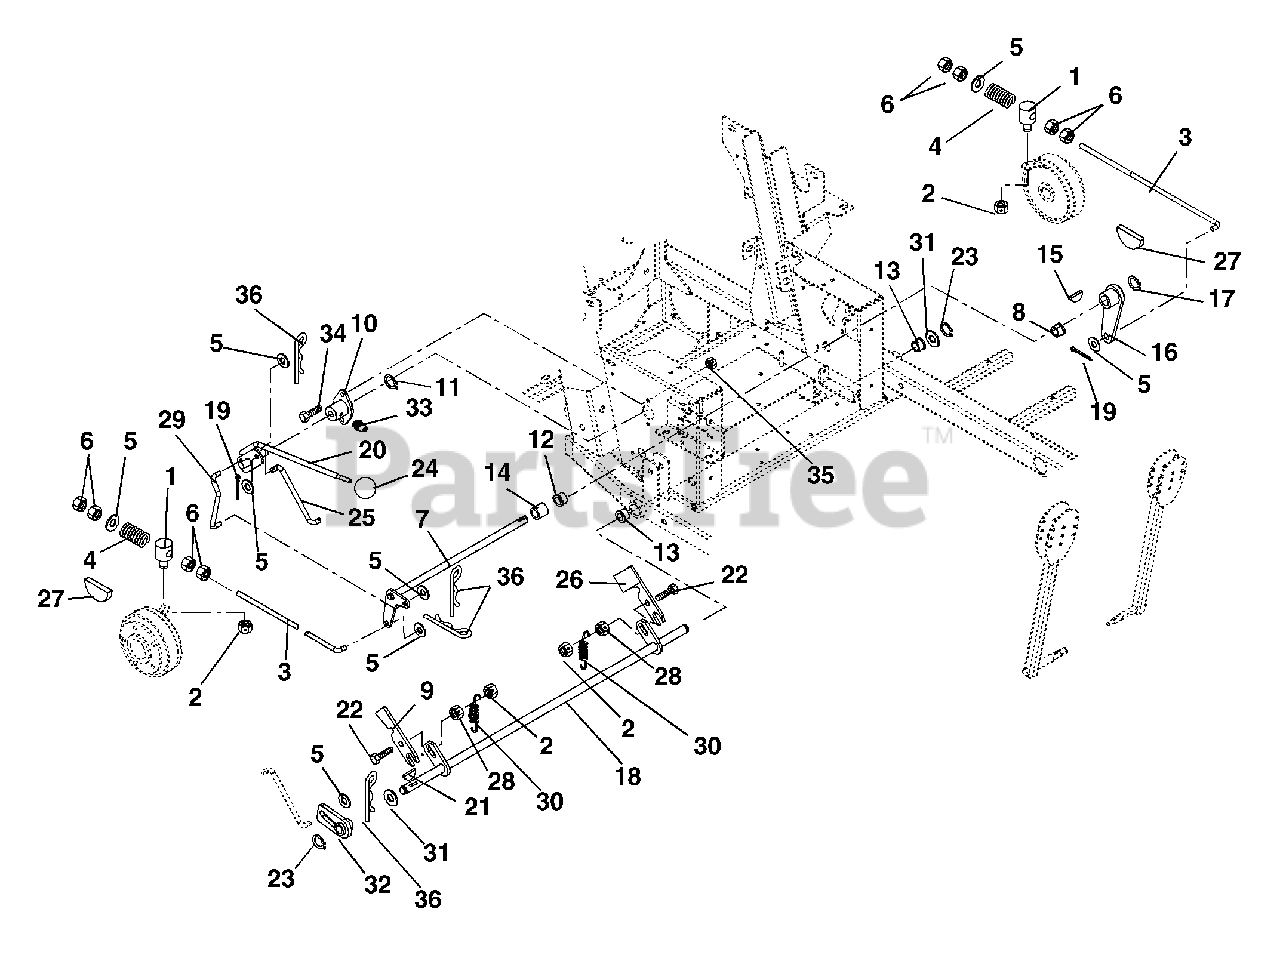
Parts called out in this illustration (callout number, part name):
1	PIN, PIVOT/TRUNNION
2	@NUT-LK-CTR .31-18 YWZC
3	PTO LINK ROD, PRO-150
4	SG-COMP .142 X .710 X 2.00
5	@WSHR-FL-STL.406X.812X.065 YWZ
6	@NUT-HEX .38-16 YWZC
7	WMT, BRAKE CROSS SHAFT
8	BSHG-FLG .630X1.000X.625 NY
9	SLIDE, INTERLOCKING BRAKE
10	BUSHING, FLANGED (WITH HOLE)
11	RG-RTNG-EXT .625X.050
12	BSHG-FLG .762X1.0X.580X1.48 NY
13	BSHG-FLG.500X.750X.750X1.000BR
14	BSHG-SLV .750X1.000X.750
15	KEY-WDRF .19X.75 HRD #9
16	WMT, BRAKE ARM
17	RG-RTNG-EXT .625X.050
18	WMT, MECHANICAL BRAKE
19	@PIN-CTR .09X.75 EXTPRSQCT YWZ
20	WMT, BRAKE ACTUATING
21	KEY-WDRF .13X.63 HRD#5
22	@BLT-HEX .31-18X1.25 GR5 YWZC
23	RG-RTNG-EXT .500X.050 (SNAP)
24	KNOB-STEERING LOCK
25	LINKAGE, BRAKE ACTUATING
26	INTERLOCK, SAFETY SWITCH
27	PAD SET, DISK BRAKE
28	@NUT-LK-TOP-FLG .31-18 YWZC
29	LINKAGE, BRAKE ACTUATING
30	SG-TENS .063X.44X1.56
31	WSHR-FL-STL .505X1.00X.062YWZC
32	WMT, PARKING BRAKE HUB
33	FTG-LUBE .25-28X.256 YWZC
34	@BLT-HEX .31-18X.75 GR5 YWZC
35	@NUT-LK-TOP-FLG .31-18 YWZC
36	PIN-HAIR, ENDRIES #25 YWZC
